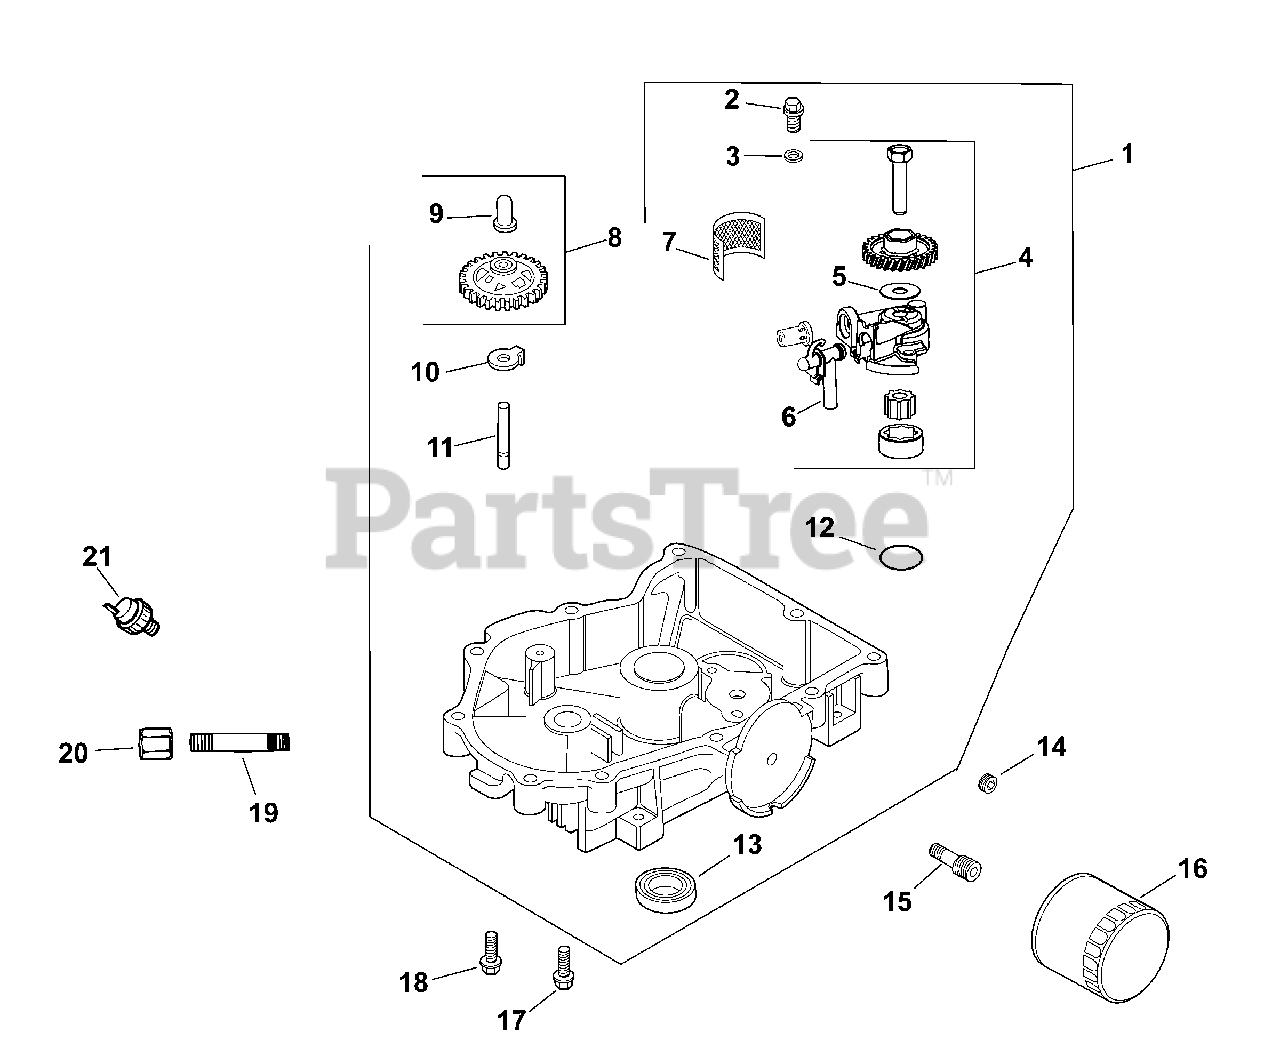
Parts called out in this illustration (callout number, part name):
1	PAN , OIL ASSEMBLY USE 24 199 32-S
2	SCREW,FLG THD FRM M6X1.0X25-(#25086395S)
3	WASHER, FLAT 6 MM
4	OIL PUMP ASSY KIT-USE 24 393 53-S
5	O-RING, OIL PICK-UP
6	KIT, OIL PICK-UP TUBE
7	SCREEN, OIL
8	KIT, GOVERNOR GEAR W/PIN
9	PIN, GOVERNOR REGULATING
10	TAB, LOCKING
11	SHAFT, GOVERNOR GEAR
13	SEAL, OIL (KM)-USE 25 032 06-S
14	PLUG, PIPE CTSK 3/8"
15	NIPPLE, OIL FILTER
16	OIL FILTER
17	SCREW, HEX FLANGE -USE 24 086 17-S
18	SCREW, FLG M8X1.25X45
19	NIPPLE, PIPE
20	CAP, PIPE
21	SWITCH, PRESSURE (CLOSED)-USE 25 099 27-
